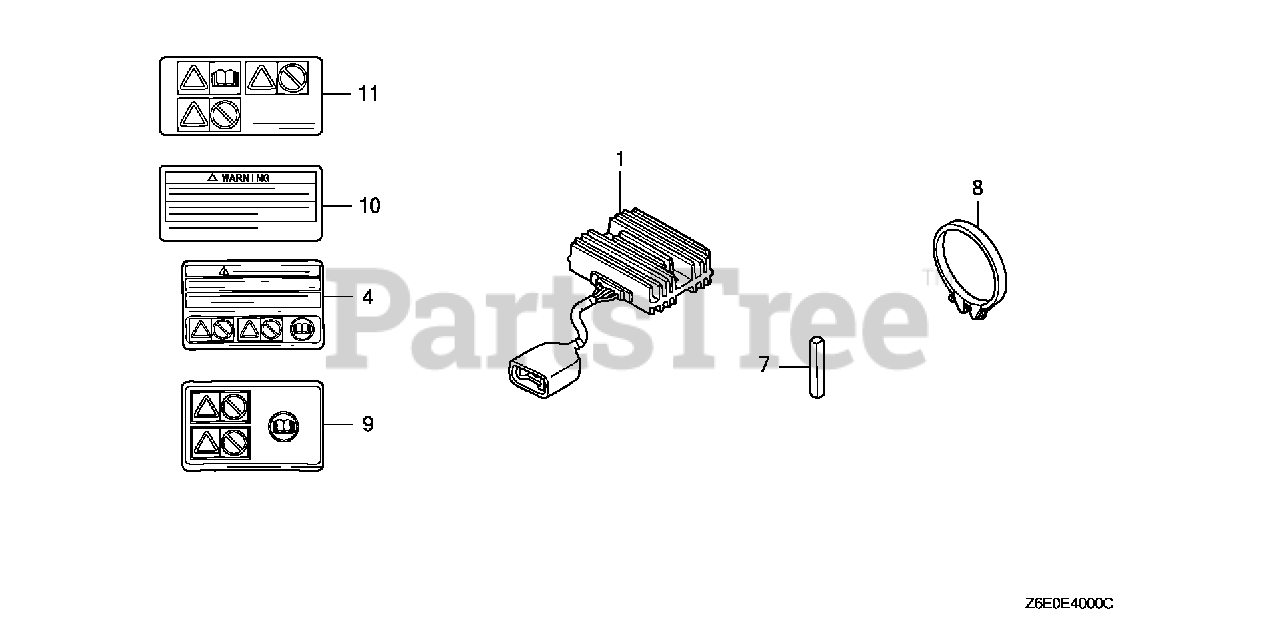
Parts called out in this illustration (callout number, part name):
4	MARK, OPERATOR CAUTION (FRENCH)(MADE IN JAPAN)
7	KEY (6.3X6.3X43)
8	BAND, AIR CLEANER CONNECTING TUBE (66)
10	MARK, OPERATOR CAUTION (FRENCH)(MADE IN JAPAN)
11	MARK, OPERATOR CAUTION (PICTOGRAPH)
